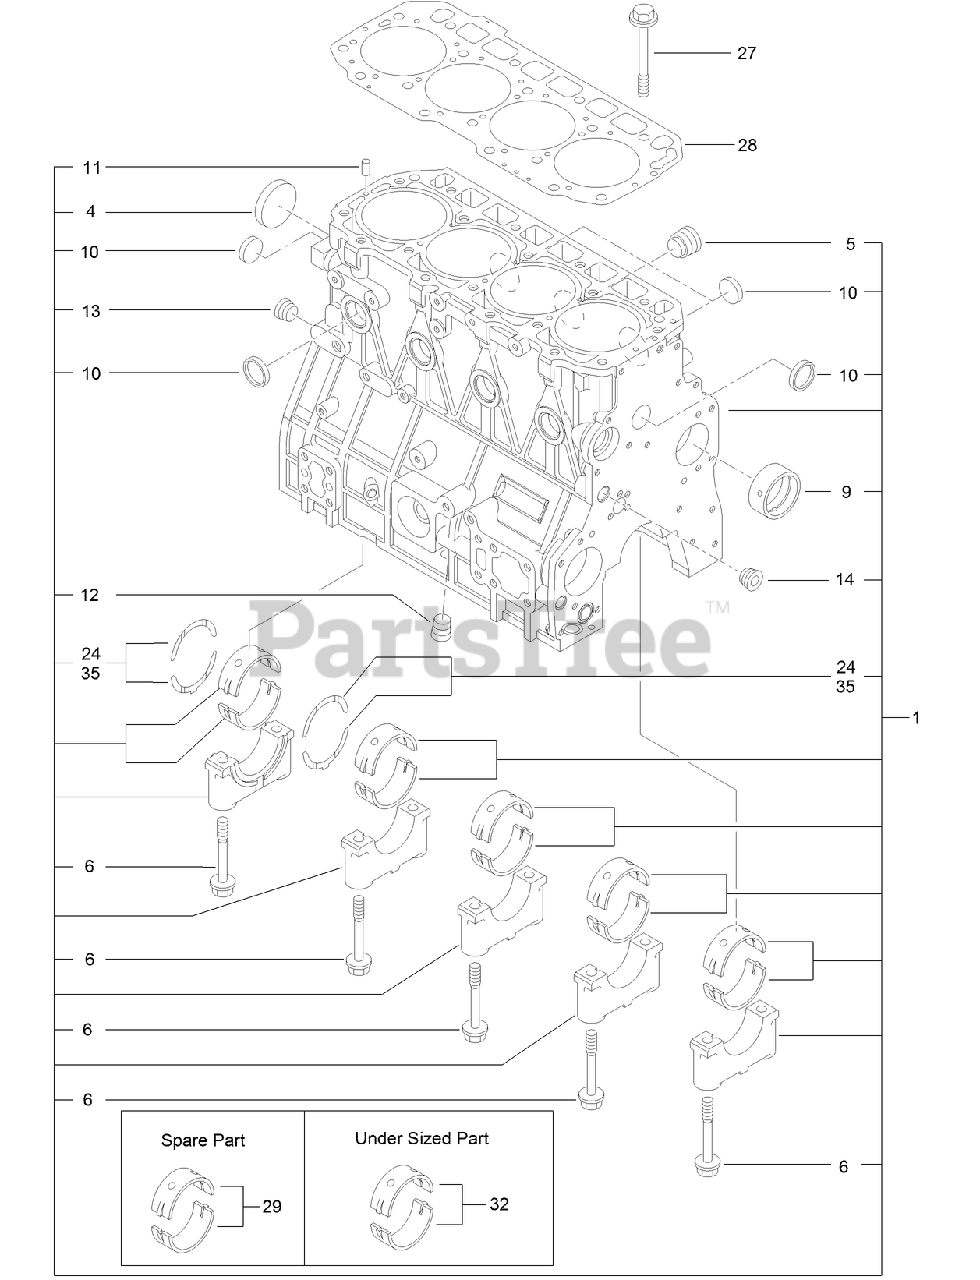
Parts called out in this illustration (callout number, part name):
1	CYLINDER BLOCK ASM
9	BUSHING-CAMSHAFT
11	PIN-SPRING
24	BEARING-THRUST
27	BOLT-HEAD
28	GASKET-HEAD, CYLINDER
29	BEARING-MAIN
32	BEARING
35	BEARING-THRUST
